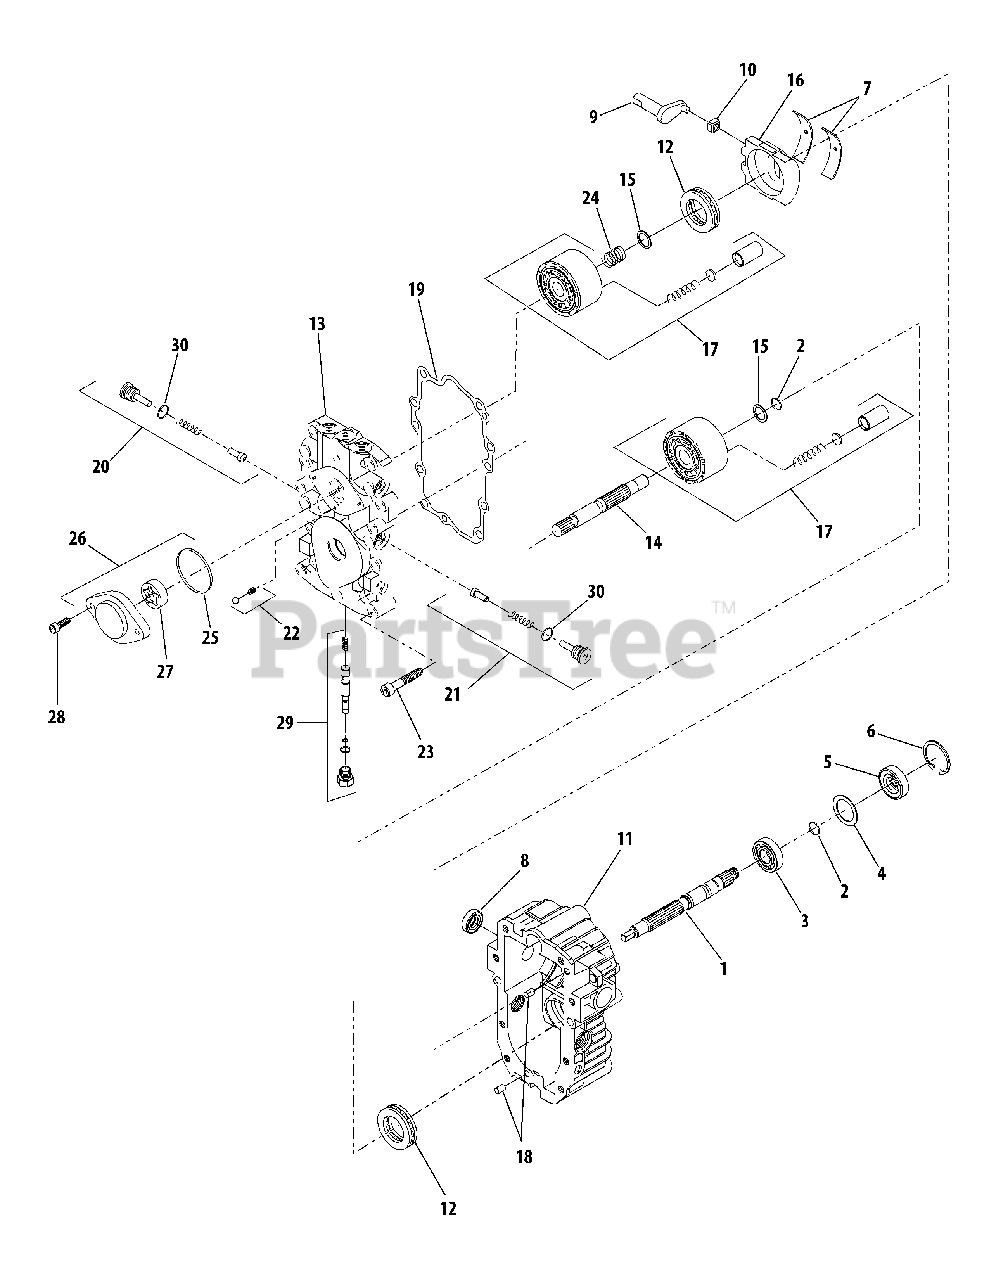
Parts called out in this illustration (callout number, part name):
1	Shaft, Pump (Splined)
2	Ring, Retaining
3	Bearing, Ball
6	Ring, Retaining
7	Bearing, Cradle
9	Arm, Trunnion
10	Guide, Slot
11	Housing Kit
12	Bearing Assembly, Thrust Ball
13	Center Section Kit
14	Shaft, Motor
15	Washer, Block Thrust
16	Swash Plate
17	Block Assembly
19	Gasket, Center Section
20	Kit, Check Valve
21	Kit, Orificed Check Valve
22	Kit, Charge Relief Valve
23	Screw, Socket Hd
24	Spring, Block
26	Kit, Charge Pump
27	Gerotor Assy
28	Screw, Socket Hd
29	Bypass Valve Kit
